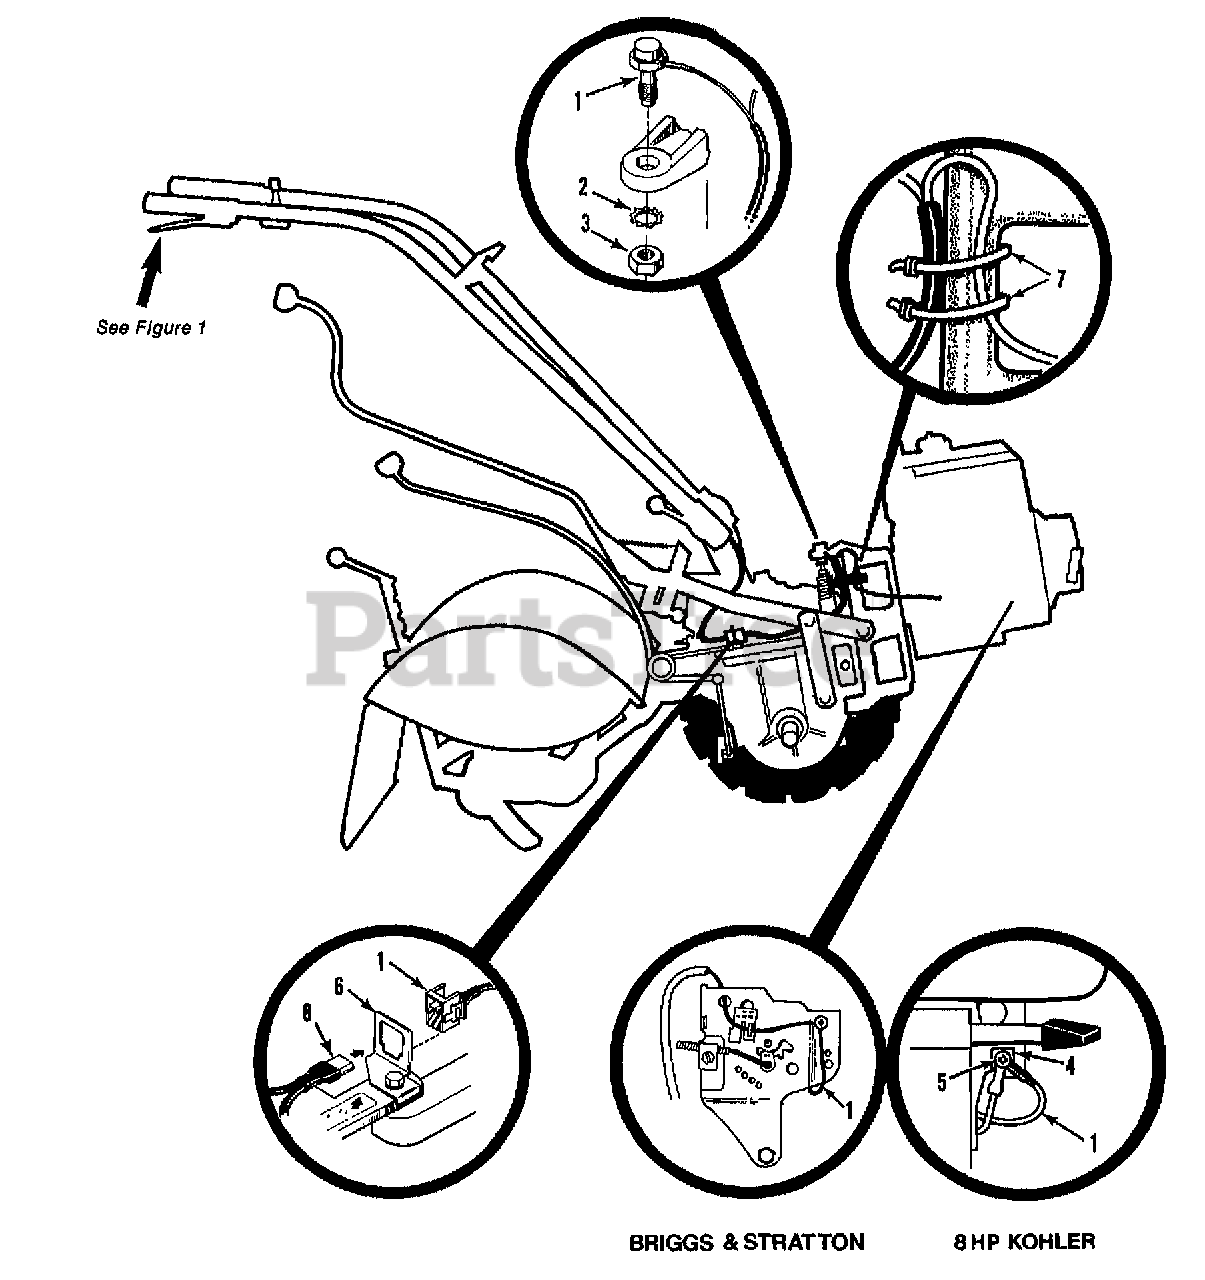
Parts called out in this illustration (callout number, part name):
1	HARNESS-WIRE ENG OPC
2	WASHER-LK .438 EXT TOOTH
3	NUT-HEX/JAM 7/16-20
4	GROMMET-7 T/L & 8 KOH OPC
5	SCR #8-18 SELF TAP
6	CLIP-CONNECTOR
7	TIE-RED
8	HARNESS-WIRE OPC HORSE
